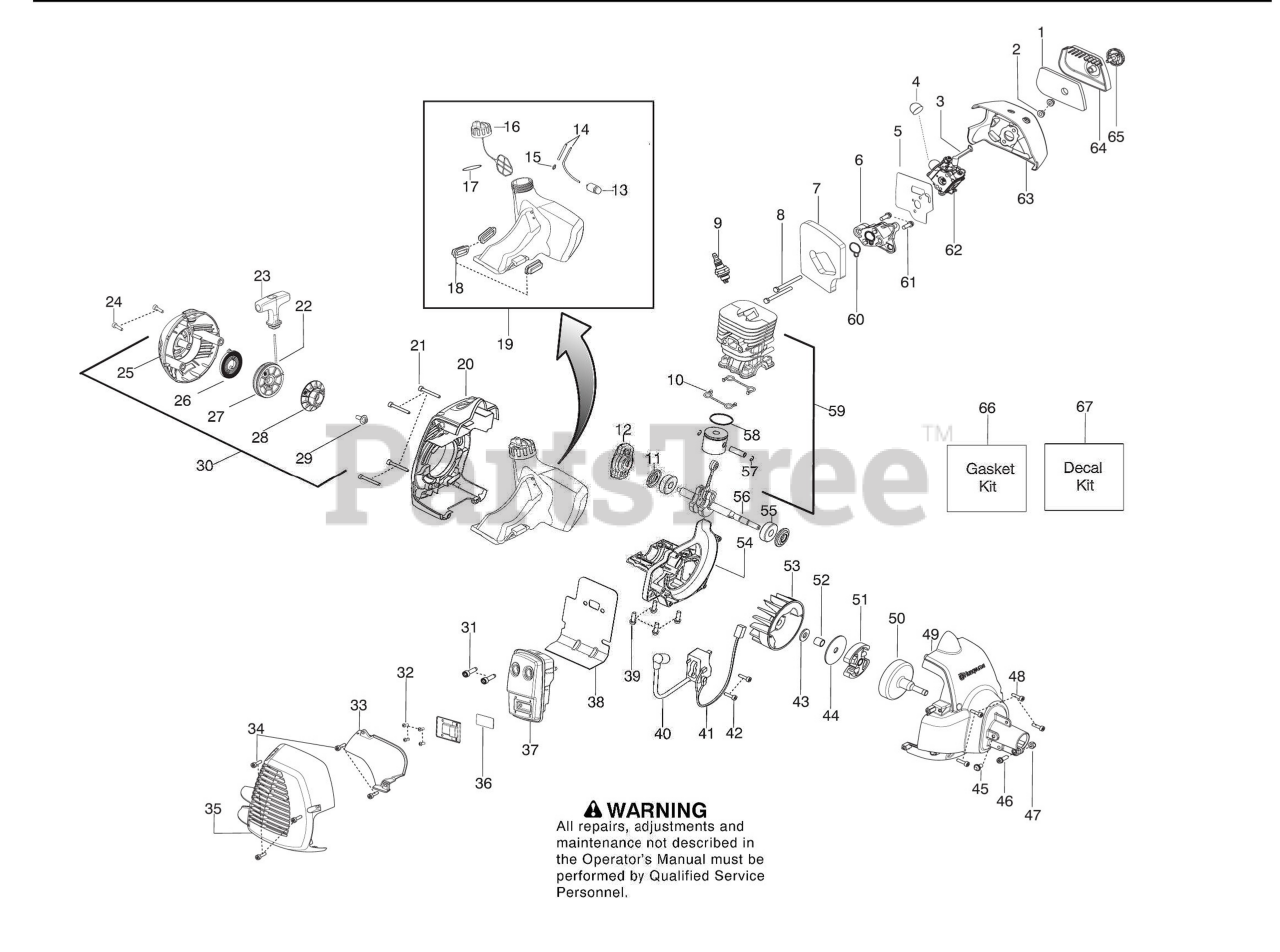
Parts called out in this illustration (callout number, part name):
2	Nut-Carb. Screw
3	Lever - Choke
4	Bulb-Purge
5	Kit-Carb. Gasket
6	Adaptor-Carb.
7	Foam-Gasket
9	Plug-Spark (RCJ-8Y)
10	Seal-Cylinder
11	Seal-Crankshaft
12	Assy-Starter Pawl
13	Assy-Fuel Filter
14	Kit-Fuel Line
15	Fitting-Fuel Line
16	Assy-Cap w/ret.
17	O-ring-Fuel Cap
18	Isolator-Fuel Tank
19	Kit-Fuel Tank Assy.
20	Shroud-Rear
22	Kit-Rope
23	Handle-Starter
25	Starter Hsg. w/eyelet
26	Kit-Starter Spring
27	Kit-Starter Pulley
28	Pulley-Driver
30	Assy-Starter Hsg.
31	Bolt-Muffler
32	Screw
33	Shield-Heat
35	Guard-Muffler
36	Kit-Spark Arrestor
37	Assy-Muffler
38	Gasket-Paper met.
41	Assy-Leadwire
44	Washer-Clutch
49	Assy-Fan Housing
50	Assy-Clutch Drum
51	Kit-Clutch Assy.
54	Crankcase
56	Assy-Crankshaft
57	Retainer-Piston Pin
58	Ring-Piston
59	Kit-Piston/Cyl.
60	Kit-Gasket
62	Kit-Carb.
63	Airbox
64	Cover-Air Box
66	Kit-Gasket
